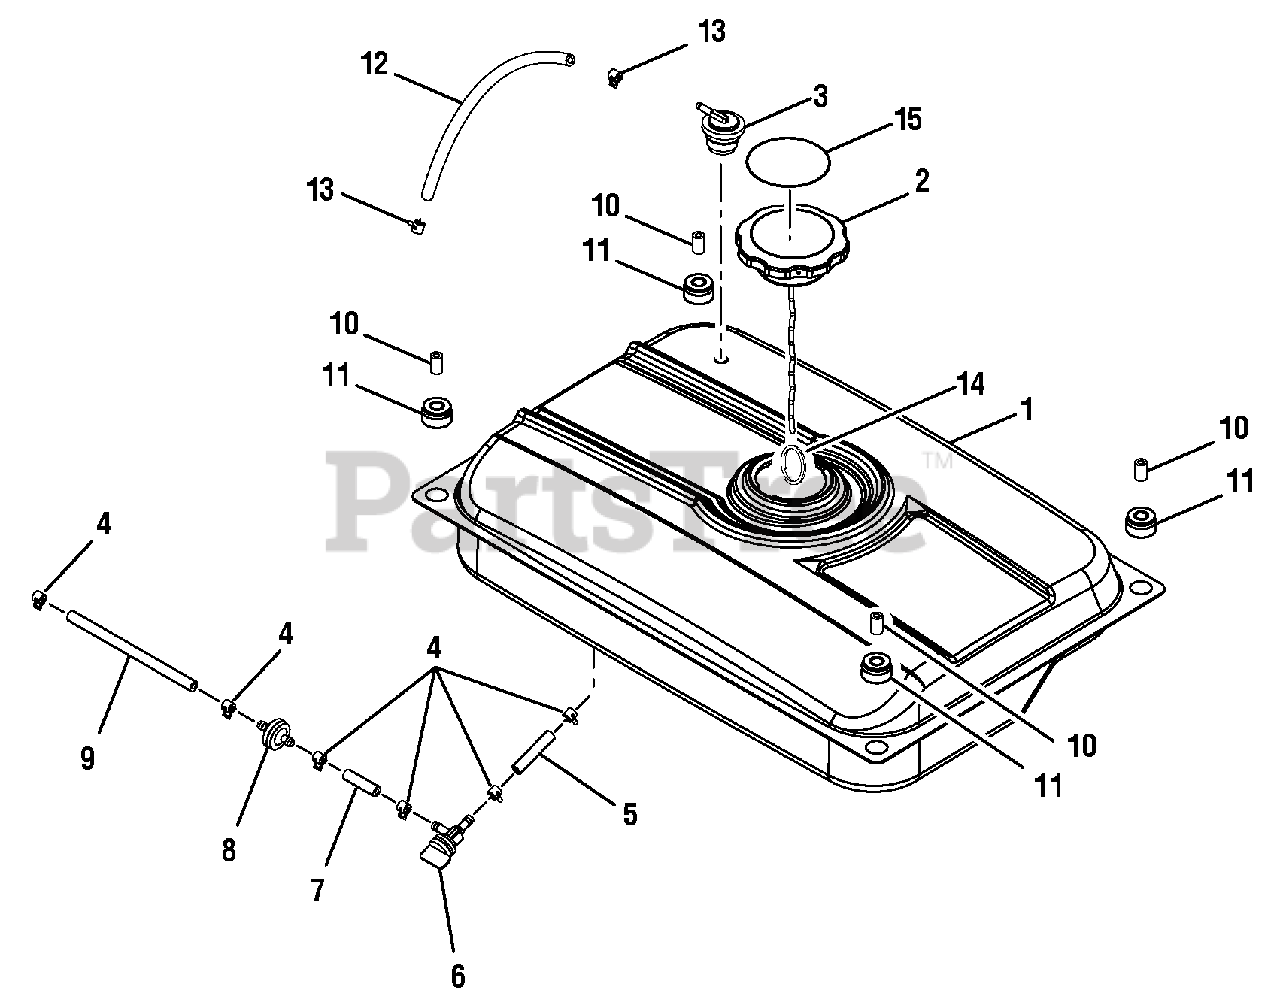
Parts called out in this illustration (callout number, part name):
1	Fuel Tank
3	Vapor Vent
4	Clamp (1/2 in.)
5	Fuel Hose (45 mm)
6	Fuel Shut Off Valve
7	Fuel Hose (35 mm)
8	Fuel Filter
9	Fuel Line (144 mm)
12	Vent Hose
13	Fuel Line Clamp (7/16 in.)
14	Ring Clip
15	Fuel Stabilizer Label
